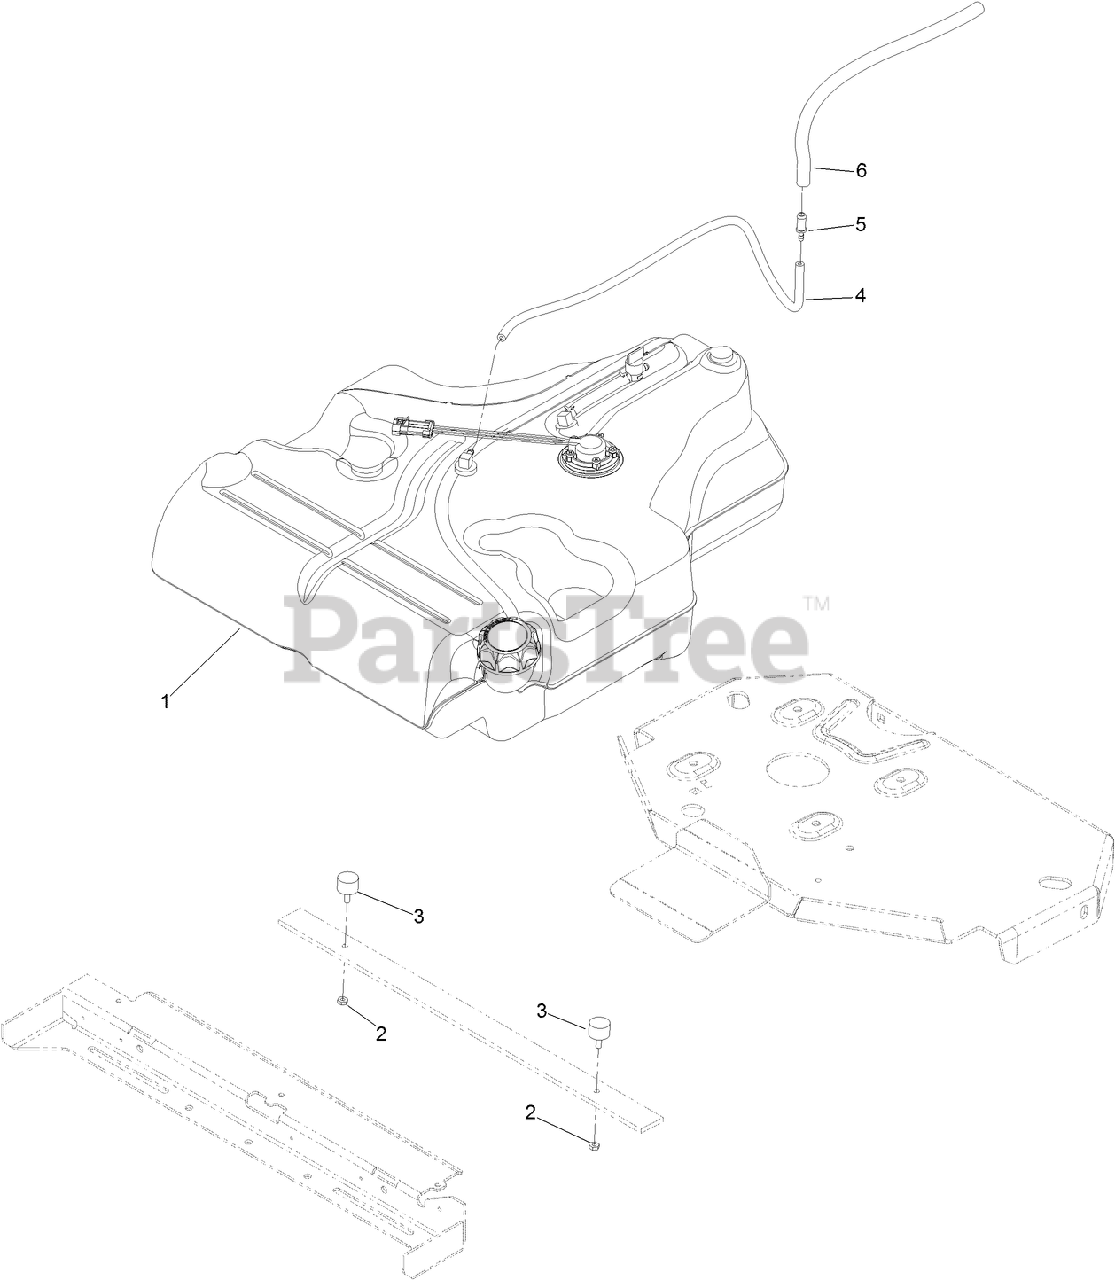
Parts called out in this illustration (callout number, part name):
1	FUEL TANK ASM
2	NUT-JAM
3	BUMPER
4	HOSE-FUEL
5	FITTING-STRAIGHT
6	HOSE-FUEL
